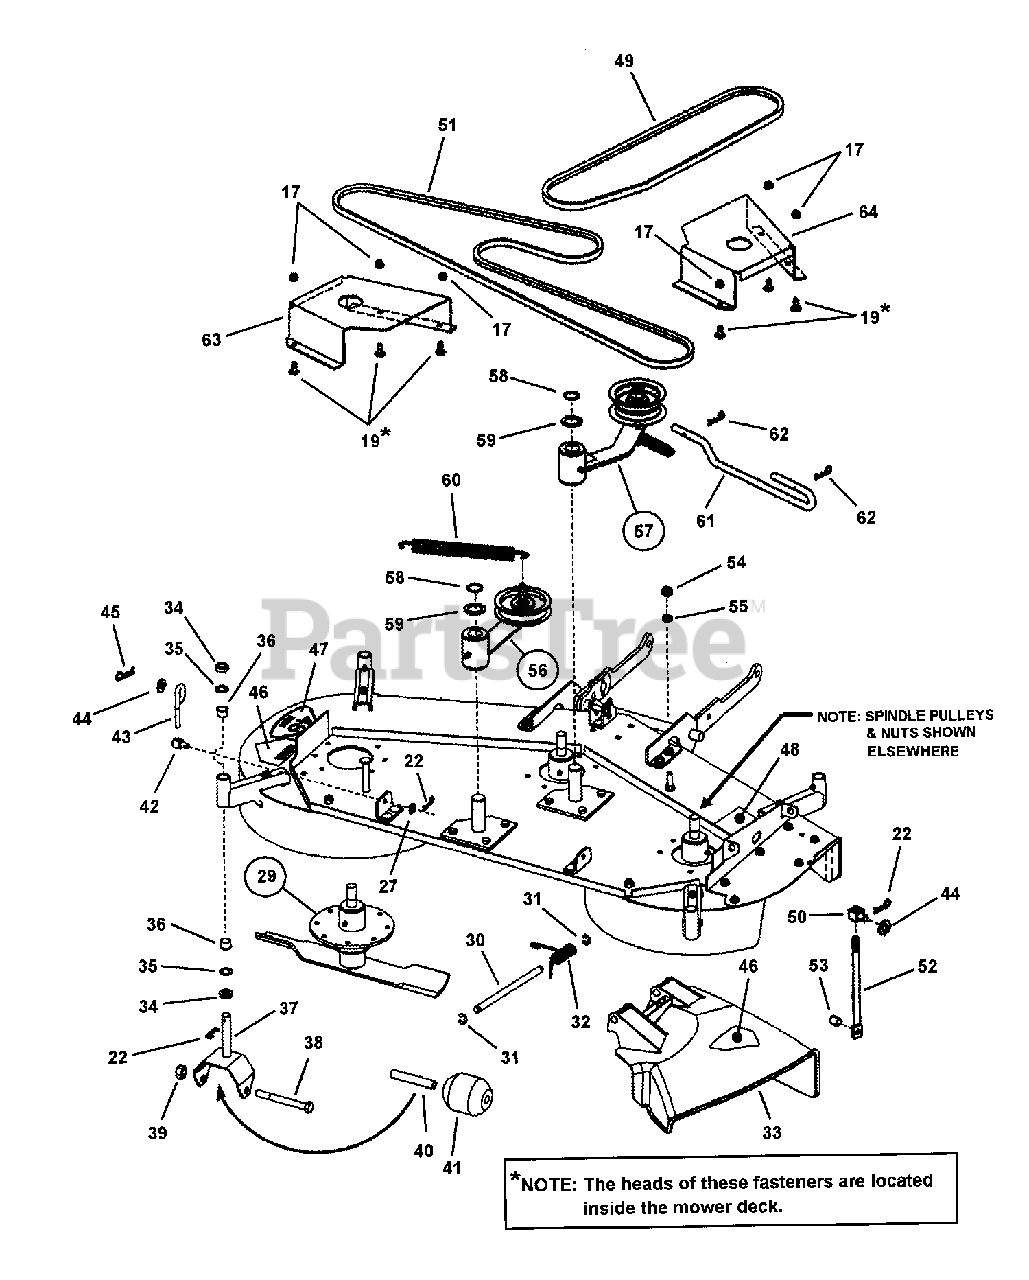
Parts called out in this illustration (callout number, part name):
17	NUT, 5/16-18 Hex Flange Lock, GR5
19	BOLT, 5/16-18 x 5/8" Short Neck Carriage, GR5
22	HAIR PIN, 3/32 x 1.5"
27	WASHER, 3/8" Flat SAE
29	ASSEMBLY, 48" Spindle
30	PIN, Chute Hinge
31	RING, Retaining
32	SPRING, Chute
33	CHUTE, Side Discharge
34	SPACER, Blade
35	WASHER, .64 x .99 x .05 Flat
36	BUSHING, Flange, .64 x .75 x .5
37	WELDMENT, Anti-Scalp Wheel
38	SCREW, 1/2-20 x 4-1/2" Hex Head Cap, GR5
39	NUT, 1/2-20 Hex Center Lock, GR5 or B
40	SLEEVE, Wheel Caster
41	ROLLER, Low Density Polyethylene
42	SWIVEL, 3/8-16 thread, .109 Hole
43	ROD, Rear Lift- 48" Deck
44	WASHER, .531 x 1.062 x .121 Flat SAE
45	COTTER PIN, 1/2" Self Lock
46	DECAL, Danger, Cut Finger
47	DECAL, 48" Deck
48	DECAL, Chute/Deflector
49	BELT, HB Sect. 52.165" effective length- 48" Deck Drive
50	SWIVEL, Lift, 1/2-13 thread
51	BELT, HA Sect., 94.50" effective length (TTK50 Traction Drive)
52	ROD, Front Lift- 48" Deck
54	NUT, 3/8-16 Hex Center Lock, GR5 or B
55	SPACER, Tie Rod
56	ASSEMBLY, Deck Idler
57	ASSEMBLY, Drive Idler Arm
58	RING, 1" External Retaining
59	BUSHING, 1" Machine
60	SPRING, Extension- Primary Idler
61	PIN, Deck Hanger Improved
62	HAIR PIN, 3/32 x 1-1/2"
63	COVER, Spindle- Left Hand
64	COVER, Spindle- Right Hand
